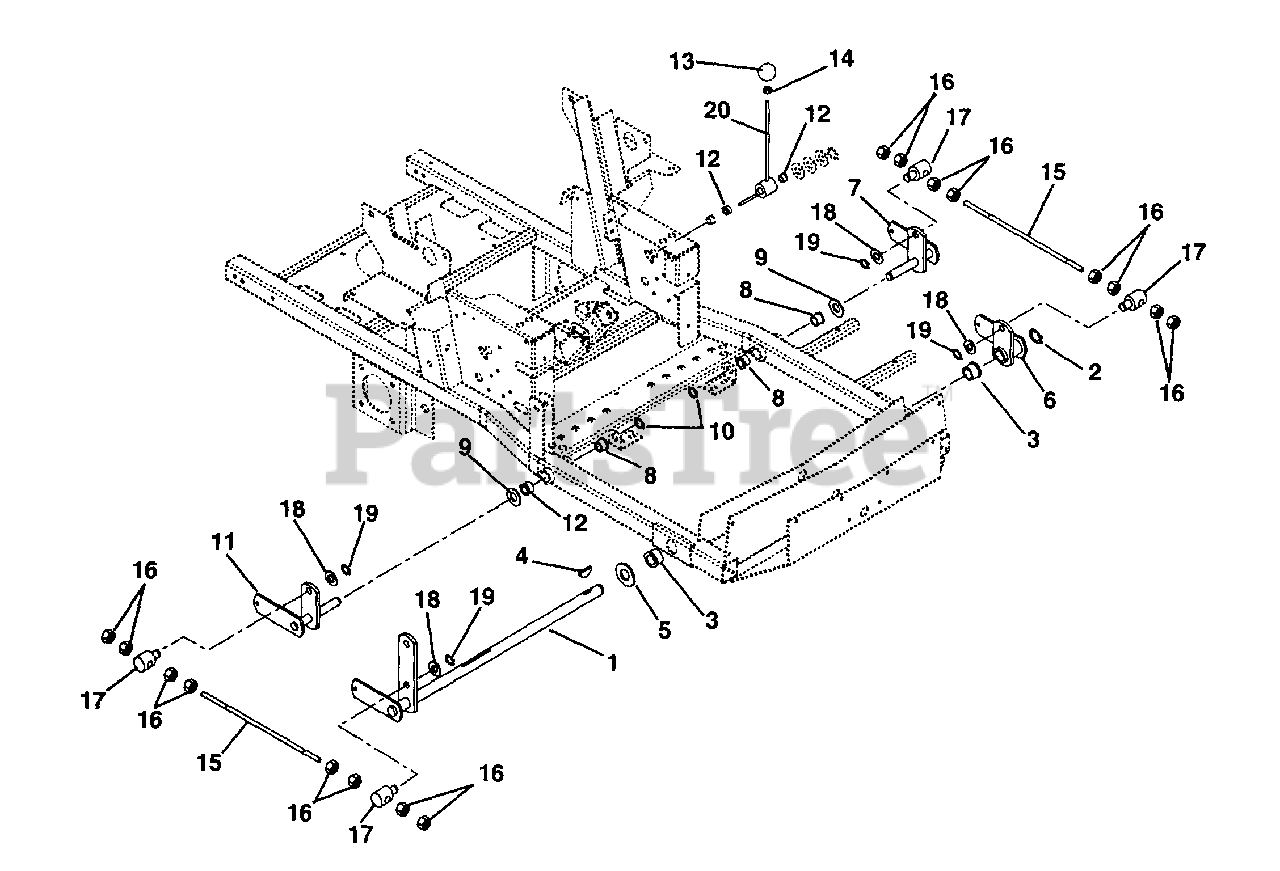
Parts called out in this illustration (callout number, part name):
1	LIFT - MOWER
2	RG-RTNG-EXT 1.00X.078
3	BSHG-FLG1.020X1.385X.75X1.75NY
4	KEY-WDRF .25X1.00 HRD #15
5	WSHR-FL-STL 1.063X2.00X.134
6	WLDM'T,LIFT ARM (FRT)
7	WLDM'T,LIFT ARM SHAFT (L.H.)
8	BSHG-FLG .762X1.0X.580X1.48 NY
9	WSHR-HDND-THRST .758X1.23X.031
10	RG-RTNG-EXT .689X.078
11	WLDM'T,LIFT ARM SHAFT (R.H.)
12	BSHG-FLG .630X1.000X.625 NY
13	KNOB-STEERING LOCK
14	NUT-HEX-JAM .375-16 YWZC
15	ROD - LIFT ASSIST
16	NUT-JAM .50-13 YWZC
17	PIVOT, MWR LIFT
18	WSHR-FL-STL .630X1.005X.062 YZ
19	RG-RTNG-EXT .625X.050
20	LEVER - DECK LIFT
